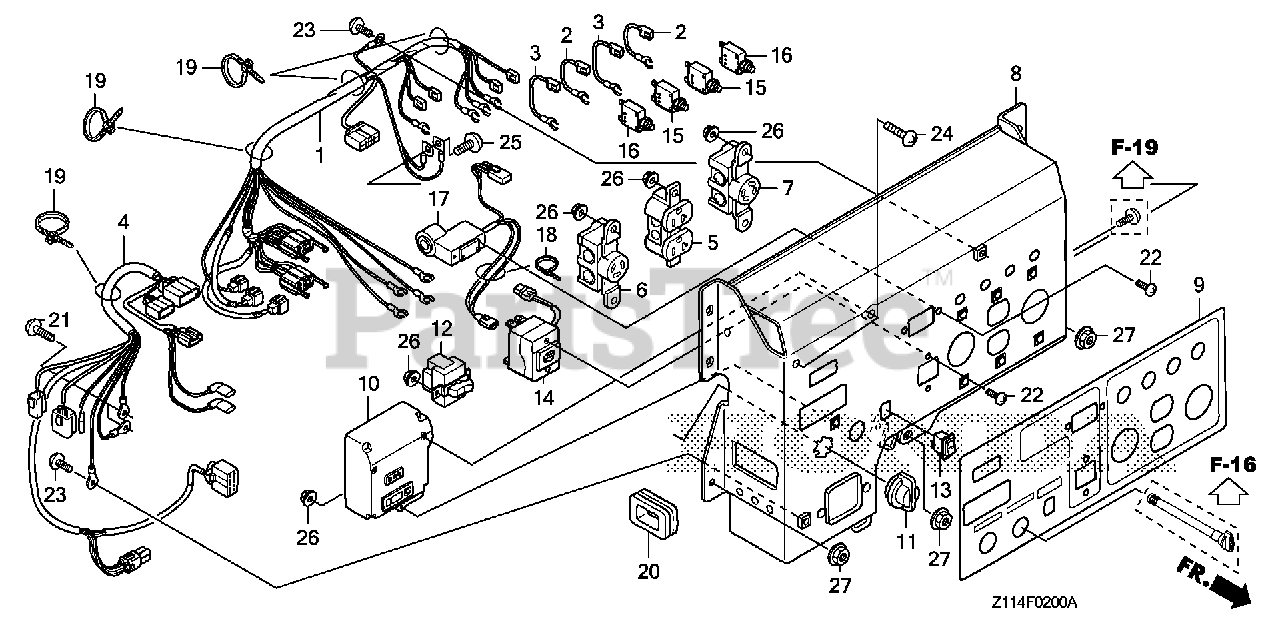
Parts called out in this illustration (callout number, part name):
1	WIRE HARNESS ASSY., MAIN
2	SUB-WIRE ASSY. (A)
3	SUB-WIRE ASSY. (D)
4	WIRE HARNESS ASSY., CONTROL
5	RECEPTACLE (20A/125V) (MATSUSHITA)
6	RECEPTACLE (30A/125V)
7	RECEPTACLE (30A/125-250V)
8	PANEL, CONTROL (EB-A)
9	MARK, PANEL (EB-A)
10	CONTROL UNIT ASSY., GENERATOR
11	SWITCH ASSY., ENGINE STOP (RED)
12	SWITCH ASSY., VOLT CHANGE
13	SWITCH, AUTO-THROTTLE
14	BREAKER, CIRCUIT (19A)
15	PROTECTOR, CIRCUIT (20A) (WHITE)
15	PROTECTOR, CIRCUIT (20A) (WHITE)(TYCO)
16	PROTECTOR, CIRCUIT (30A)
16	PROTECTOR, CIRCUIT (30A) (WHITE)
17	RELAY ASSY. (GFCI)
18	BAND, WIRE (95MM)
19	STRAP, CABLE (105MM) (BLACK)
20	GROMMET, CONTROL HARNESS
21	SCREW, PAN (3X8)
22	SCREW, PAN (4X6)
23	SCREW, PAN (5X8)
24	SCREW, PAN (5X12)
25	SCREW, PAN (6X8)
26	NUT, FLANGE (4MM)
27	NUT, FLANGE (6MM)
